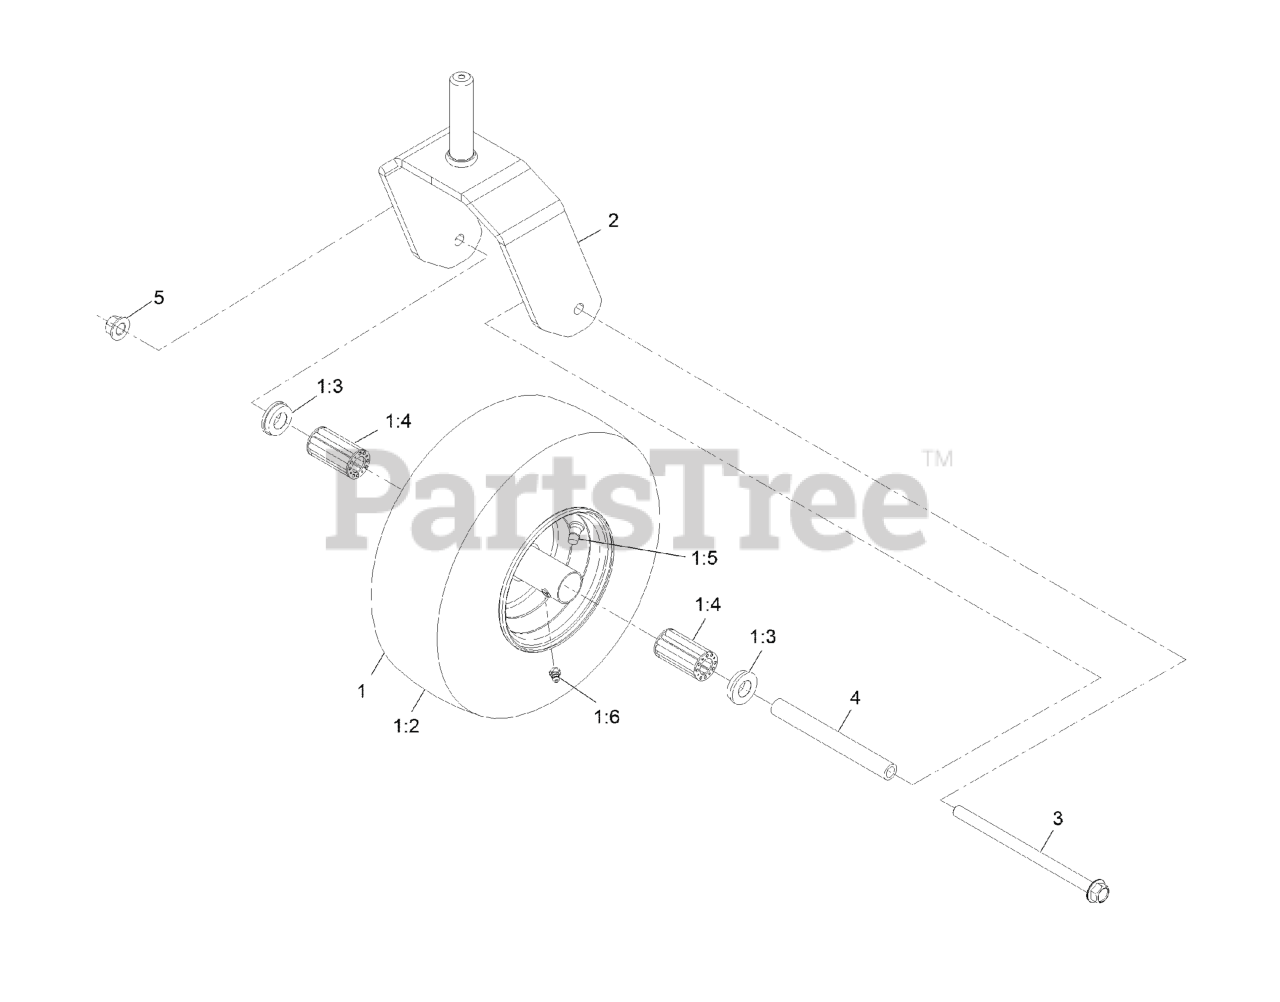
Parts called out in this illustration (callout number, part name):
1	ASM-WHEEL AND TIRE 13X6.50-6
1:3	BUSHING-FLANGE
1:4	BEARING-ROLLER, WHEEL
1:5	VALVE
1:6	FITTING-ZERK
2	FORK-CASTER
3	SCREW-HHF
4	SPANNER-WHEEL, CASTER
5	Nut-Lock 1/2-13
